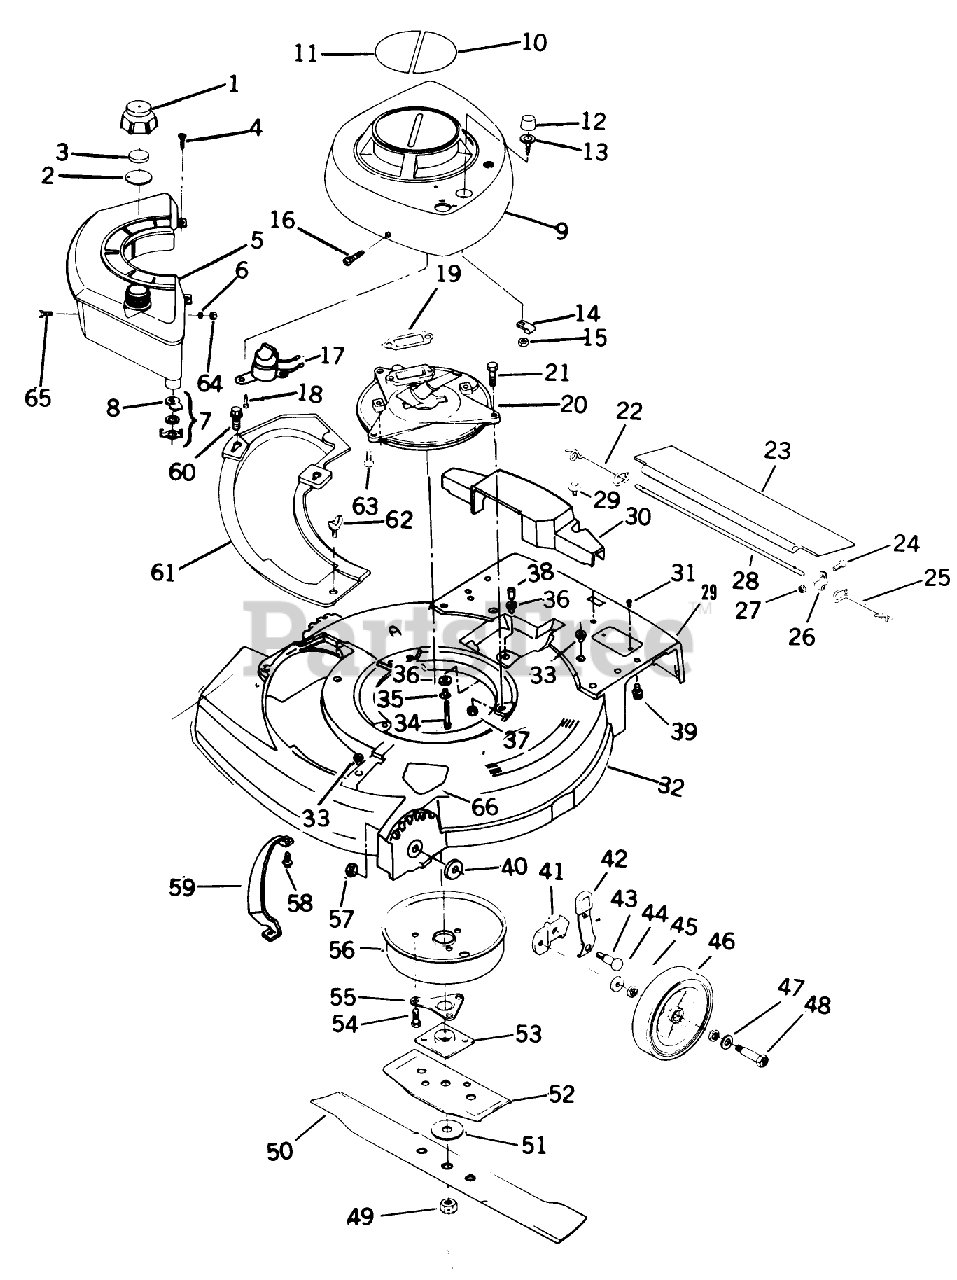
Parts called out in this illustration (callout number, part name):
2	GASKET S
3	BAFFLE - FOAM SM
4	SCREW F
5	Fuel Tank
7	SHUT OFF VALVE KIT
10	Decal-Fuel Instructions
11	Decal-Start Instructions
15	LOCKNUT S
16	SCREW F
21	SCREW
22	SPRING;TRAILING SHIELD RH
23	SHIELD
25	SPRIG T/SHLD ASOC
26	CLAMP ROD KMC
27	LOCKNUT E
28	ROD 21" ADVANCE
29	SCREW SEMS TRM HEX HD
35	SPACER ECK PRES
36	GROMMET
37	NUT-LOCK F
38	SPACER
39	SCREW
40	WASHER
44	WASHER WROUGHT
45	WASHER
46	WHEEL & TIRE KIT
47	SPACER
48	BOLT WHEEL
49	NUT-BLADE
51	WASHER
53	PLATE AND COLLAR ASM
54	SCREW
55	SUPPORT F
57	LOCKNUT
59	BAR-TOE
62	WING SCREW LAWRE
63	SCREW V
